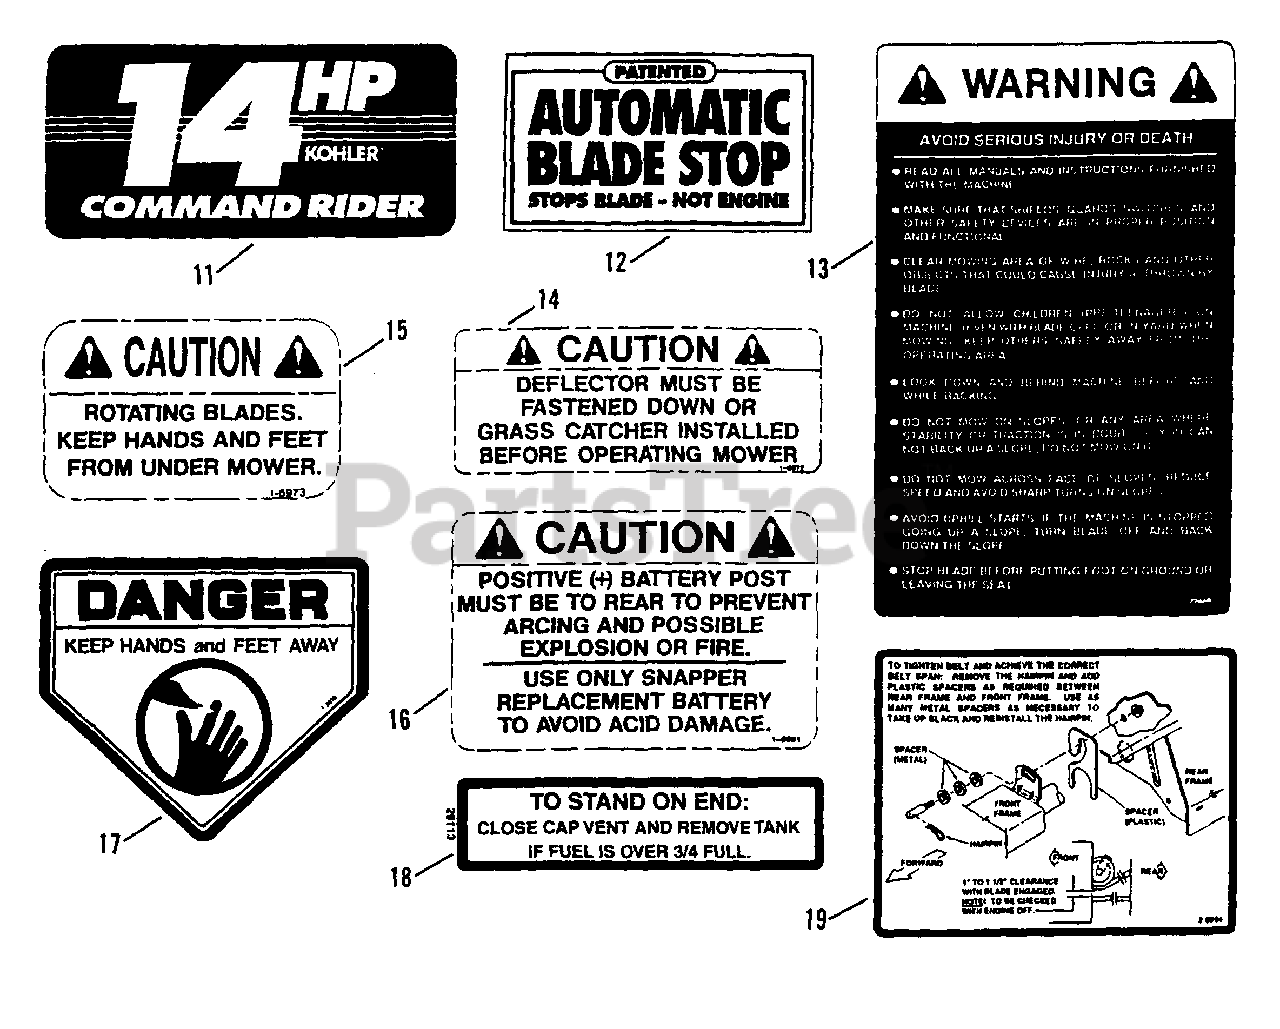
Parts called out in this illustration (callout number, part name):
11	DECAL, 14 HP
12	DECAL, Automatic Blade Stop (Point of Purchase Decal)
13	DECAL, Safety Instruction Warning
14	DECAL, CAUTION, Deflector
15	DECAL, CAUTION, Rotating Blades
16	DECAL, CAUTION, Battery
17	DECAL, DANGER
18	DECAl, CAUTION, Fuel
19	DECAL, Belt Adjustment
